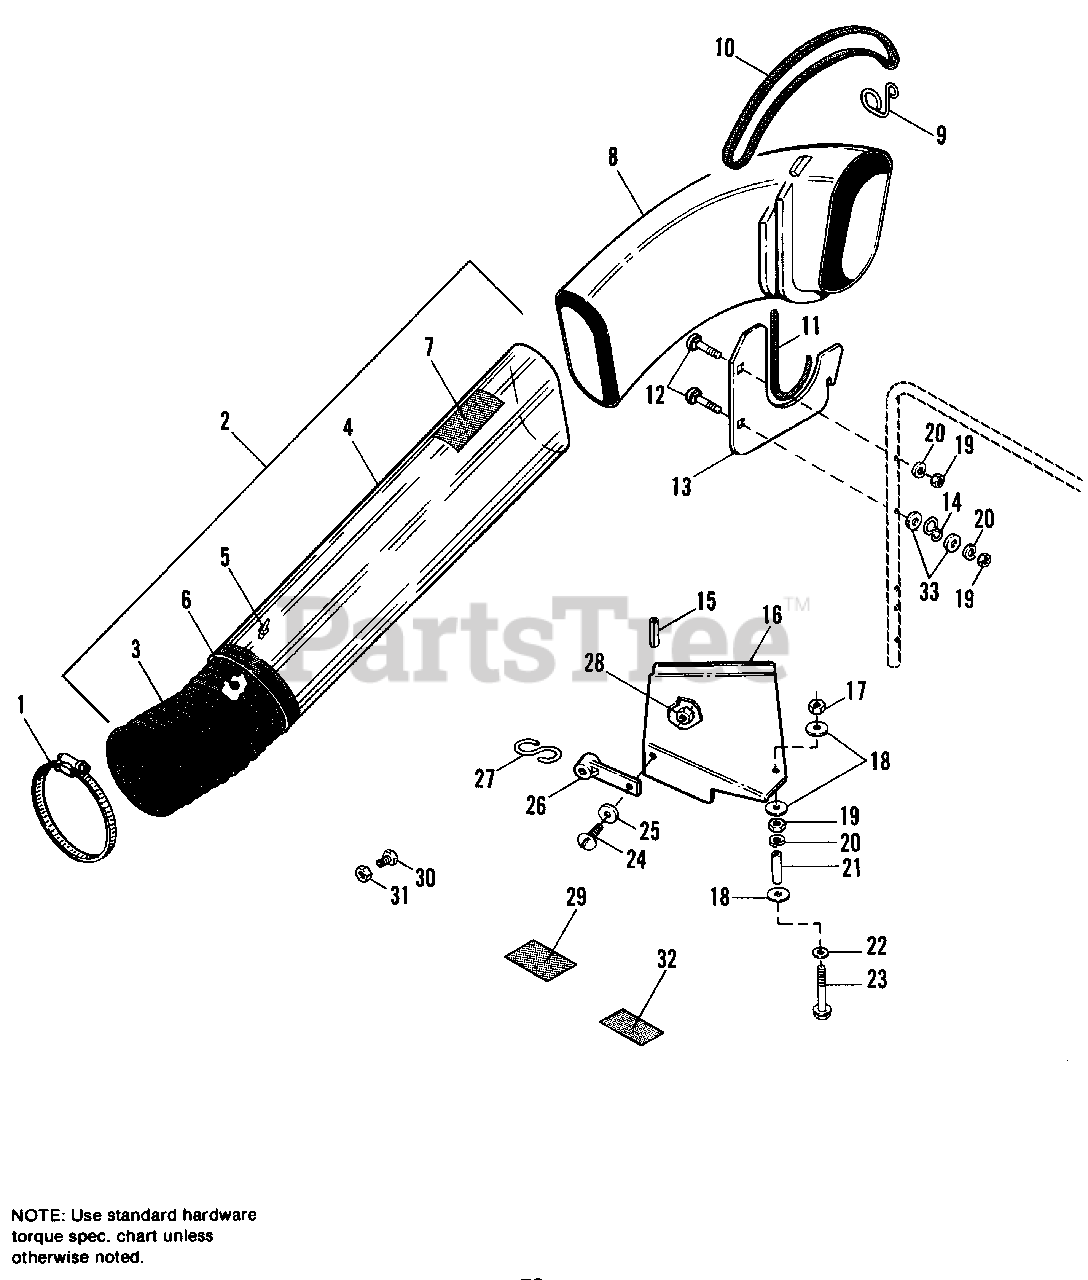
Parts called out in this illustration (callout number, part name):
2	TUBE ASSY., 38" (Incl. Ref. Nos. 3 - 7)
3	HOSE, Exhaust
6	WASHER, Rivet
7	DECAL, Cleaning Instructions
8	ELBOW, Tube to Catcher
9	HOOK, Strap
10	STRAP, Rubber
12	CARRIAGE BOLT, 5/16-18 x 1-3/4
13	BRACKET, Saddle
16	COVER ASSY., Arbor
17	NUT, Hex, Centerlock, 5/16-18
18	WASHER, 5/16
19	NUT, Hex, Full, 5/16-18
20	LOCKWASHER, 5/16
22	WASHER, Plain, 5/16
23	CAPSCREW, Hex Hd., 5/16-18 x 5-1/2
24	SCREW, Truss Hd., #10-32 x 1/2
25	WASHER, Plain
26	STRAP, Arbor Cover
28	NUT, Hex, Centerlock, #10-32
29	DECAL, Warning, Cover
30	CAPSCREW, Hex Hd., 3/8-16 x 3/4
31	NUT, Hex, Full Lock, 3/8-16
32	DECAL, Warning
33	WASHER, Plain, 5/16
